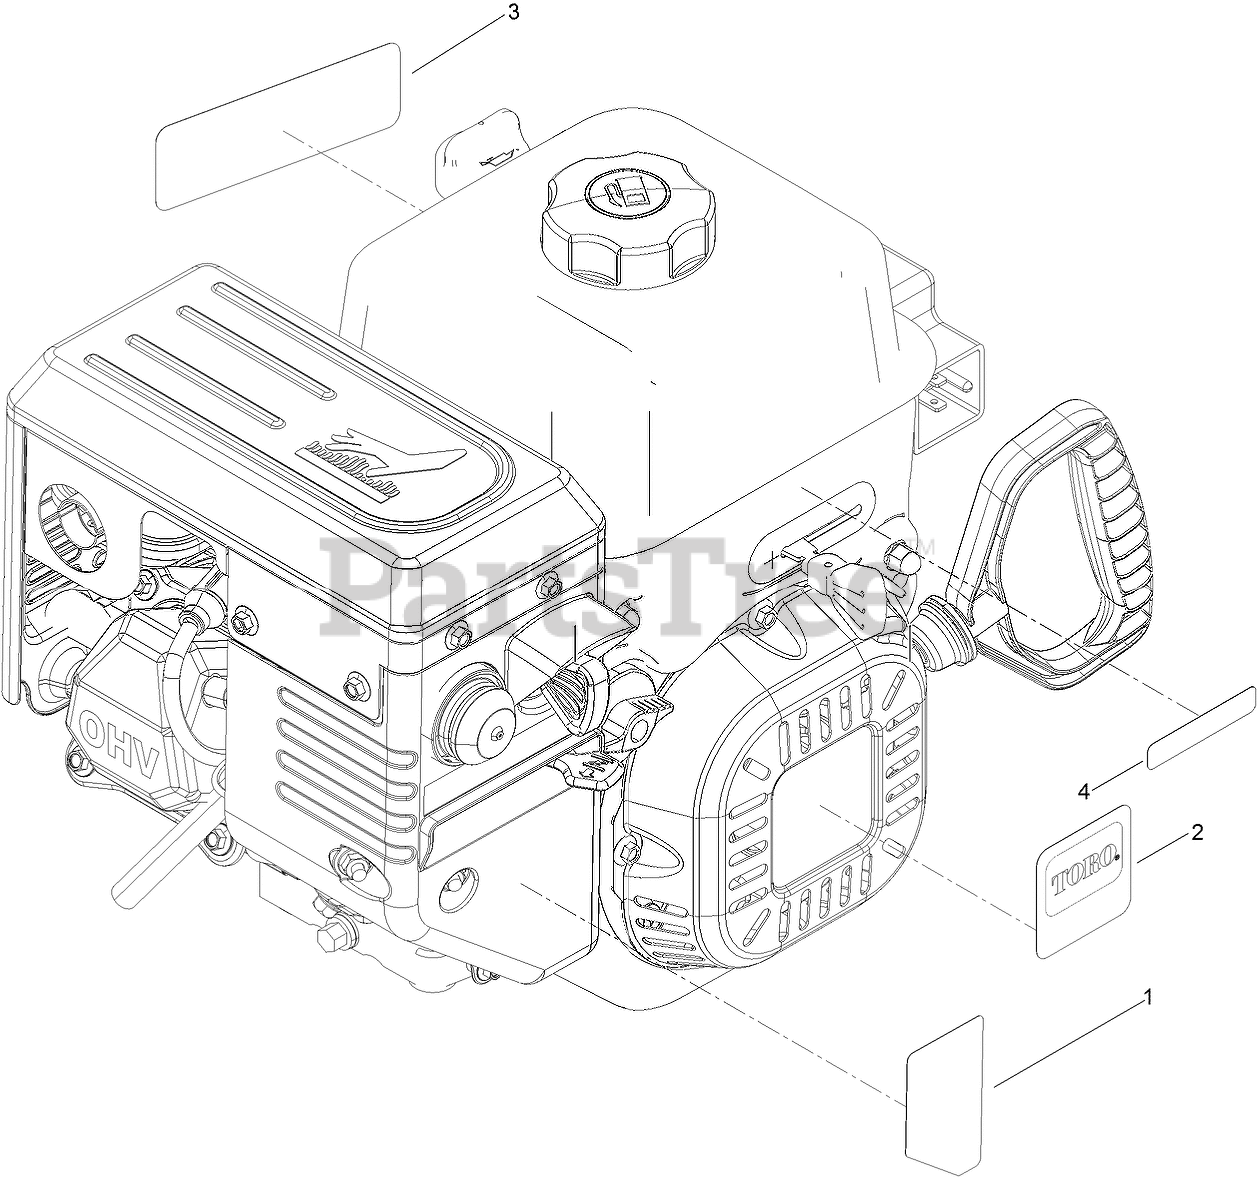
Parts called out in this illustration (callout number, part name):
1	DECAL-CONTROL, ENGINE
2	DECAL-ENGINE, SERIES G210
3	DECAL-RECOIL, G210
4	DECAL-THROTTLE
